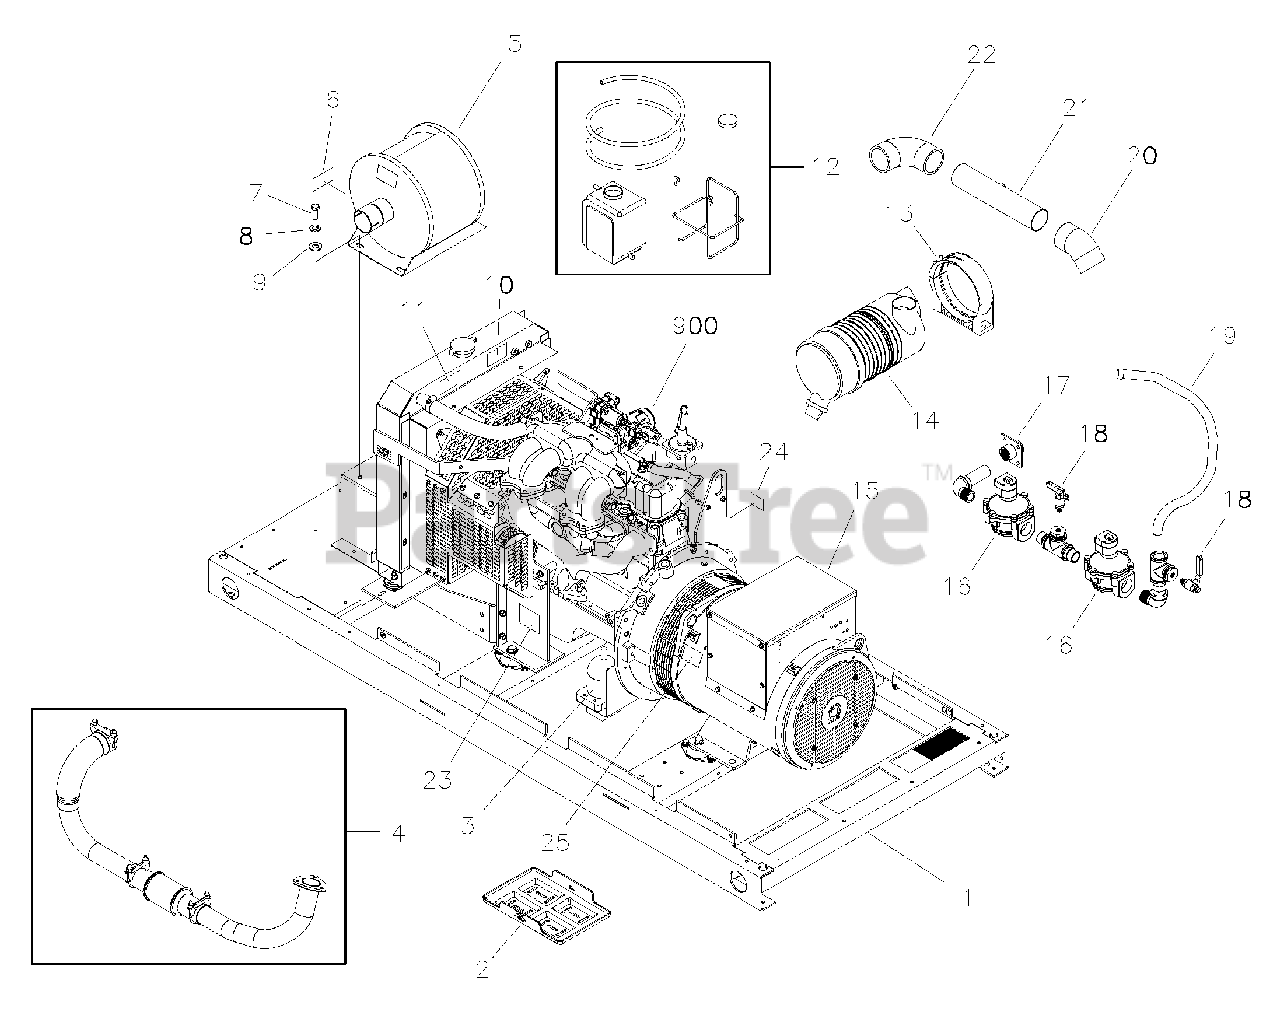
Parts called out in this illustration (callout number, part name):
1	BASE
3	ASSY, Heater, Tank
5	SILENCER, Muffler
6	DECAL, Burn Hazard
7	HHCS, 5/16 - 18 x 1
8	WASHER, 5/16 - M8, Lock
9	WASHER, 5/16 - M8, Flat
10	DECAL, Warning Hot Coolant
11	DECAL, Warning Moving Parts
12	KIT, Bottle Overflow
13	CLAMP, Air Cleaner
14	ASSY, Air Cleaner
15	ASSY, Alternator
16	ASSY, Fuel Valve
17	COUPLER, Fuel System
18	VALVE, Ball 1/4"
19	ASSY, Hose, Fuel
21	TUBE, Inlet, Air
23	DECAL, Warning, Hot
24	DECAL, Oil Drain
25	DECAL, Explosion Hazard
900	** ENGINE
